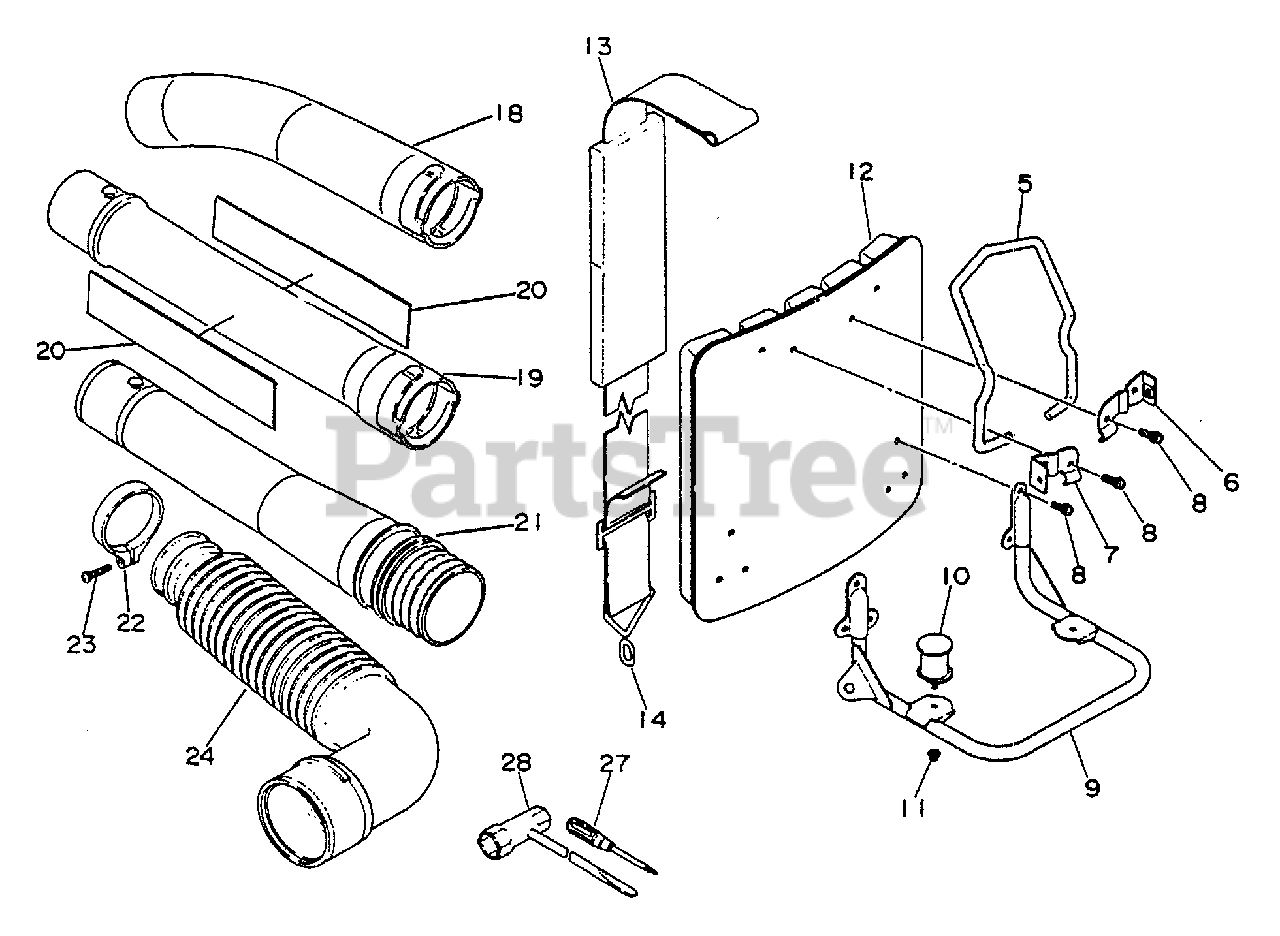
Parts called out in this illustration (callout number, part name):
7	BRACKET, HANGER
8	SCREW - 5X10
11	NUT - 6 -- FLANGE
13	BACKPACK STRAP ASSY
14	RING, STRAP
18	TUBE, BLOWER - CURVED
19	TUBE, BLOWER - STRAIGHT
20	LABEL - ECHO
21	TUBE, BLOWER - SWIVEL
22	CLAMP KIT
23	SCREW - 5X25
24	TUBE, BLOWER - FLEXIBLE
27	SCREWDRIVER - (+)
28	T-WRENCH - 10X19mm
